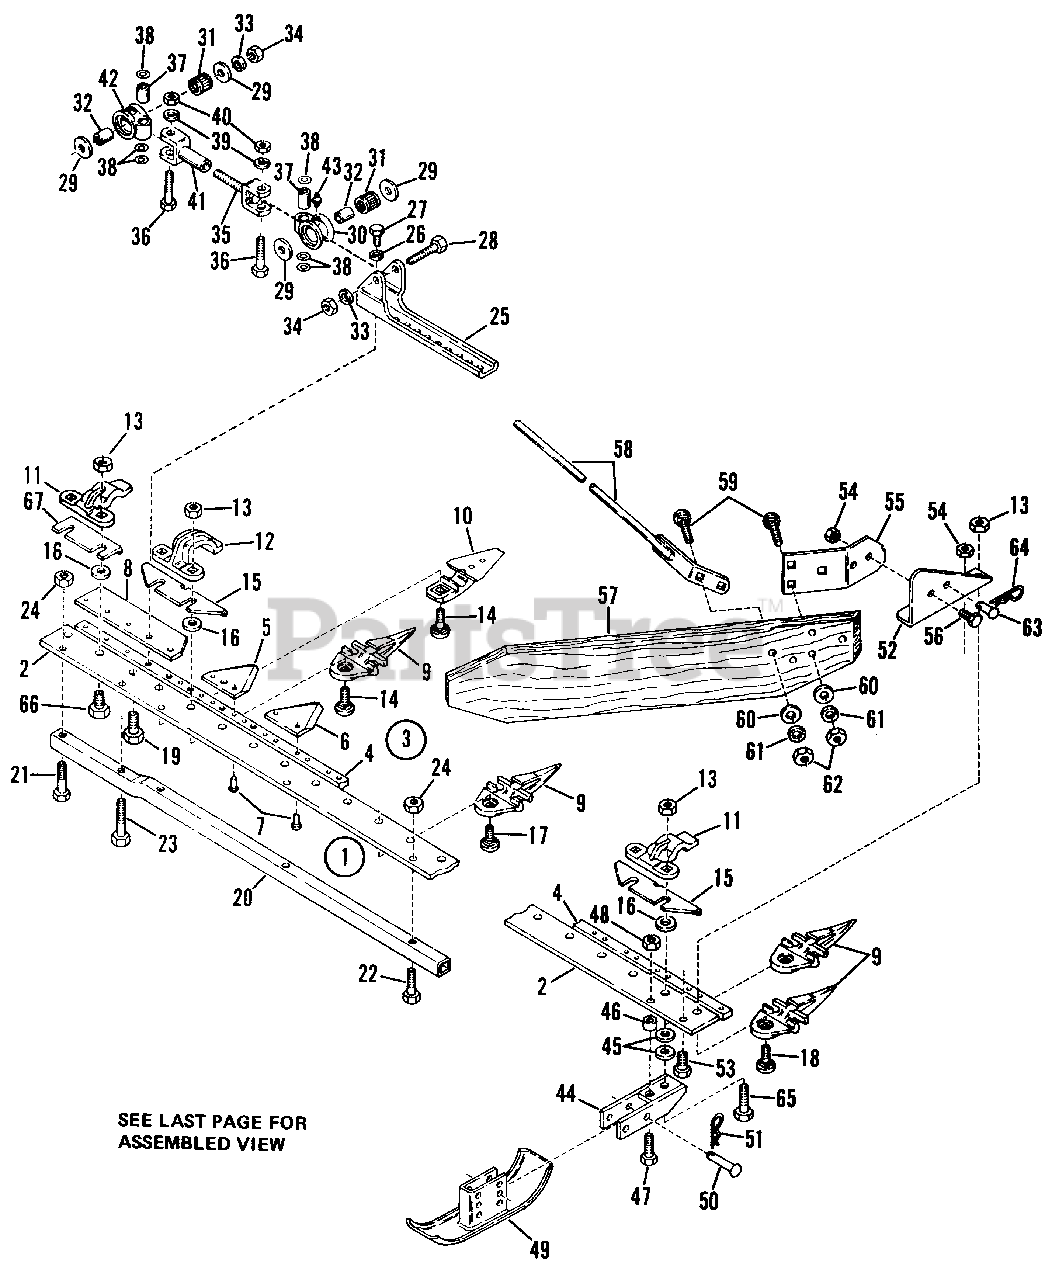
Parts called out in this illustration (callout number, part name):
1	Cutter Bar Assembly (Incl. Ref. Nos. 2 thru 18)
2	BAR, Cutter
3	Blade Assembly (Incl. Ref. Nos. 4 thru 8)
5	SECTION, Knife
6	SECTION, Knife
8	BAR, Filler
10	Shear Finger Assembly
11	CLIP, Bar
12	CLIP, Bar
13	Full Lock Hex. Nut, 7/16"-14 N.C.
14	Carriage Bolt, 7/16"-14 x 1-1/2"
15	PLATE, Wear
16	WASHER, Plain
17	Carriage Bolt, 7/16"-14 x 1" lg.
18	CAP, Fuel Tank
19	Hex. Capsrew, Gr. 5, 7/16"-14 x 1-1/4"
20	TUBE, Square
21	Hex Cap Screw, 3/8"-16 N.C. x 2-1/4" SAE Grade 5
22	Screw, Cap, Hex., 3/8"-16 N.C. x 1-3/4" lg.
23	Hex Head Capscrew, 3/8"-16 x 2-3/4"
24	Nut, Lock, Hex Hd., Full, 3/8"-l6 N.C.
25	HEAD, Sickle
26	Lockwasher, External 1/4" (Mfg. Nos. 953 & 954)
27	Hex Head Capscrew, 5/16"-24 x 3/4"
28	Hex Head Capscrew
30	HOUSING, Pitman Bearing
31	BEARING, Needle (Pitman)
33	Lockwasher 7/16" Henry #918199
34	Nut-Hex.-Full 7/16"-14 N.C. Henry #918213
35	Clevis Assembly
36	Crankshaft
37	BEARING, Pivot Block
38	WASHER, 5/8
39	Lockwasher, 3/8" (Mfg. Nos. 920 & 953)
40	Nut-Hex.-Full 3/8"-16 N.C. Henry #916950
41	Clevis Assembly
42	HOUSING, Bearing Pitman
43	Fitting, Grease, Alemite No. 1641
44	Support Assembly
45	Plain Washer, 5/16" (Mfg. Nos. 953 & 954)
47	SCREW, Hexagon Head Cap 3/8"-16 N.C. x 1-1/2" Large
48	Nut, Lock, Hex Hd., Full, 3/8"-l6 N.C.
49	Shoe Assembly
50	PIN, Round Head Drilled, 3/8 x 2-3/8
51	CLIP, Spring (Serviced in 5 pk)
53	CAPSCREW, 7/16"-20 NF x 3/4" Hex Head, Large
54	Nut, Lock, Hex Hd., Full, 3/8"-l6 N.C.
55	SUPPORT, Divider Board
56	Bolt, Carriage, 3/8"-16 NC x 1" lg.
57	BOARD, Divider
58	Divider Rod Assembly
59	Bolt, Carriage, 3/8"-16 NC x 1-1/2" lg.
60	Plain Washer, 5/16" (Mfg. Nos. 953 & 954)
61	Lockwasher, 3/8" (Mfg. Nos. 920 & 953)
62	Nut-Hex.-Full 3/8"-16 N.C. Henry #916950
63	Pin, 3/8" dia. x 1" lg., Round Head Rivet
64	CLIP, Spring (Serviced in 5 pk)
65	Hex Capscrew. 7/16"-14 x 2" lg.
66	Hex. Cap Screw, 7/16"-14 x 1-1/2"
67	PLATE, Wear
